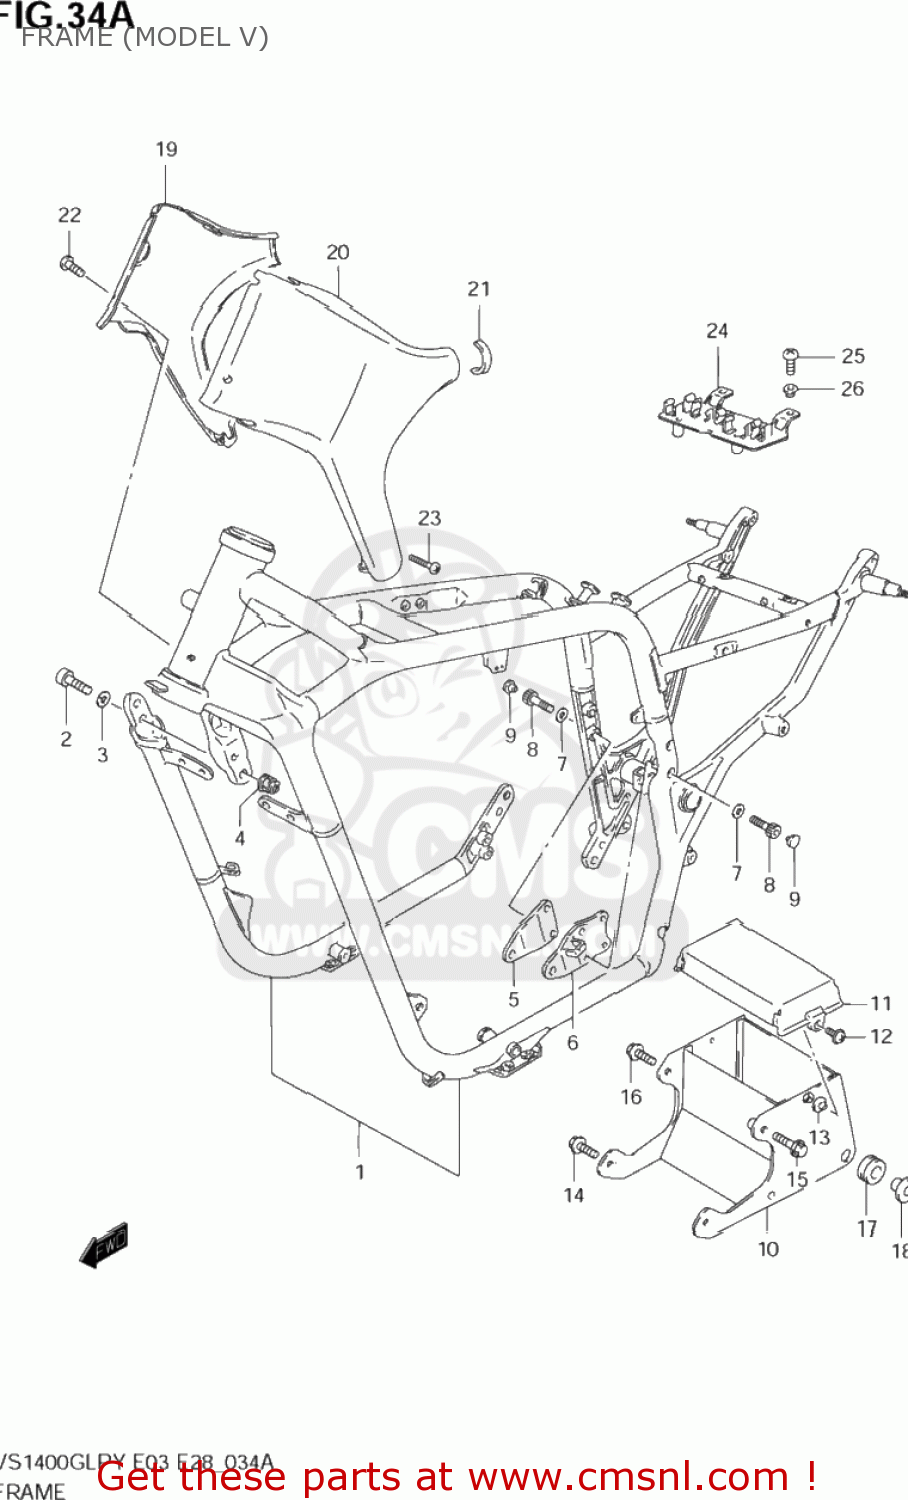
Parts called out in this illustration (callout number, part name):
1	FRAME SET(BLUE)
2	BOLT(10X33)
3	WASHER
4	NUT
5	PLATE,ENG MTG NO.4,R
6	PLATE,ENGINE MOUNT NO.4,L
7	WASHER
8	BOLT(8X32)
9	CAP(OD:14.5)
10	HOLDER,BATTERY
11	COVER,BATTERY
12	SCREW(5X12)
13	WASHER
14	BOLT
15	BOLT
16	BOLT(8X40)
17	CUSHION
18	BUSH
19	COVER COMP,FRAME HEAD
20	COVER COMP,FRAME HEAD
21	PROTECTOR,FRAME HEAD COVER
22	SCREW 6X10
23	SCREW
24	HOLDER,COUPLER
25	SCREW
26	WASHER
